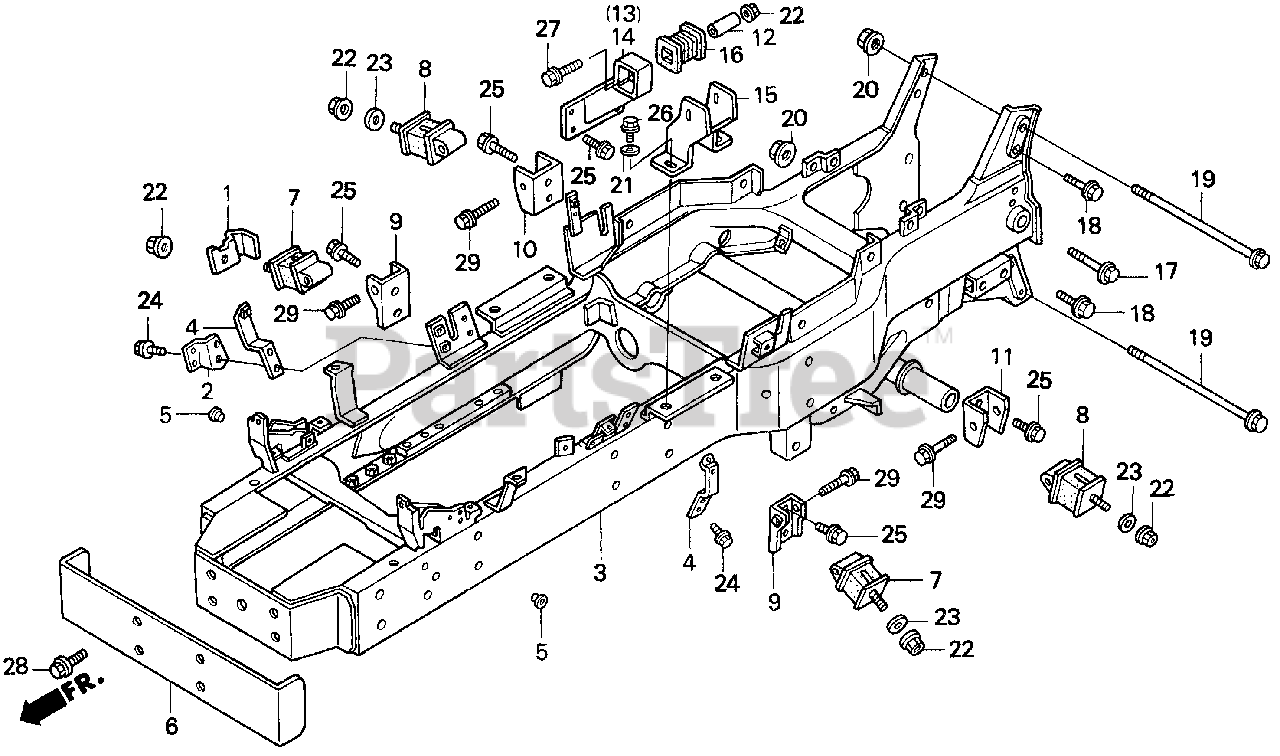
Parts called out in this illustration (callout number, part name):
1	BRACKET F, WIRE HARNESS CLIP
2	BRACKET, WIRE HARNESS CLIP (D)
3	FRAME *R165* (JOLLY RED)
4	BRACKET, SKIRT CENTER
5	CAP, HOLE (13MM)
6	PLATE, FR.
7	RUBBER, FR. ENGINE MOUNTING
8	RUBBER, RR. ENGINE SETTING
9	BRACKET, FR. ENGINE MOUNTING
10	BRACKET, R. RR. ENGINE MOUNTING
11	BRACKET, L. RR. ENGINE MOUNTING
12	COLLAR, ROLL STOPPER
13	ARM, R. MID ROLL STOPPER
14	ARM, L. MID ROLL STOPPER
15	BRACKET, MID ROLL STOPPER
16	RUBBER, ROLL STOPPER INSULATOR
17	BOLT, SPECIAL (14X63)
18	BOLT, FLANGE (14X38)
19	BOLT, FLANGE (14X242)
20	NUT, SPECIAL (14MM)
21	WASHER, BRAKE PEDAL
22	NUT, FLANGE (10MM)
23	WASHER, PLAIN (10MM)
24	BOLT, FLANGE (6X14)
25	BOLT, FLANGE (10X20)
26	BOLT, FLANGE (10X28)
27	BOLT, FLANGE (10X65)
28	BOLT, FLANGE (12X30)
29	BOLT, FLANGE (10X50)
